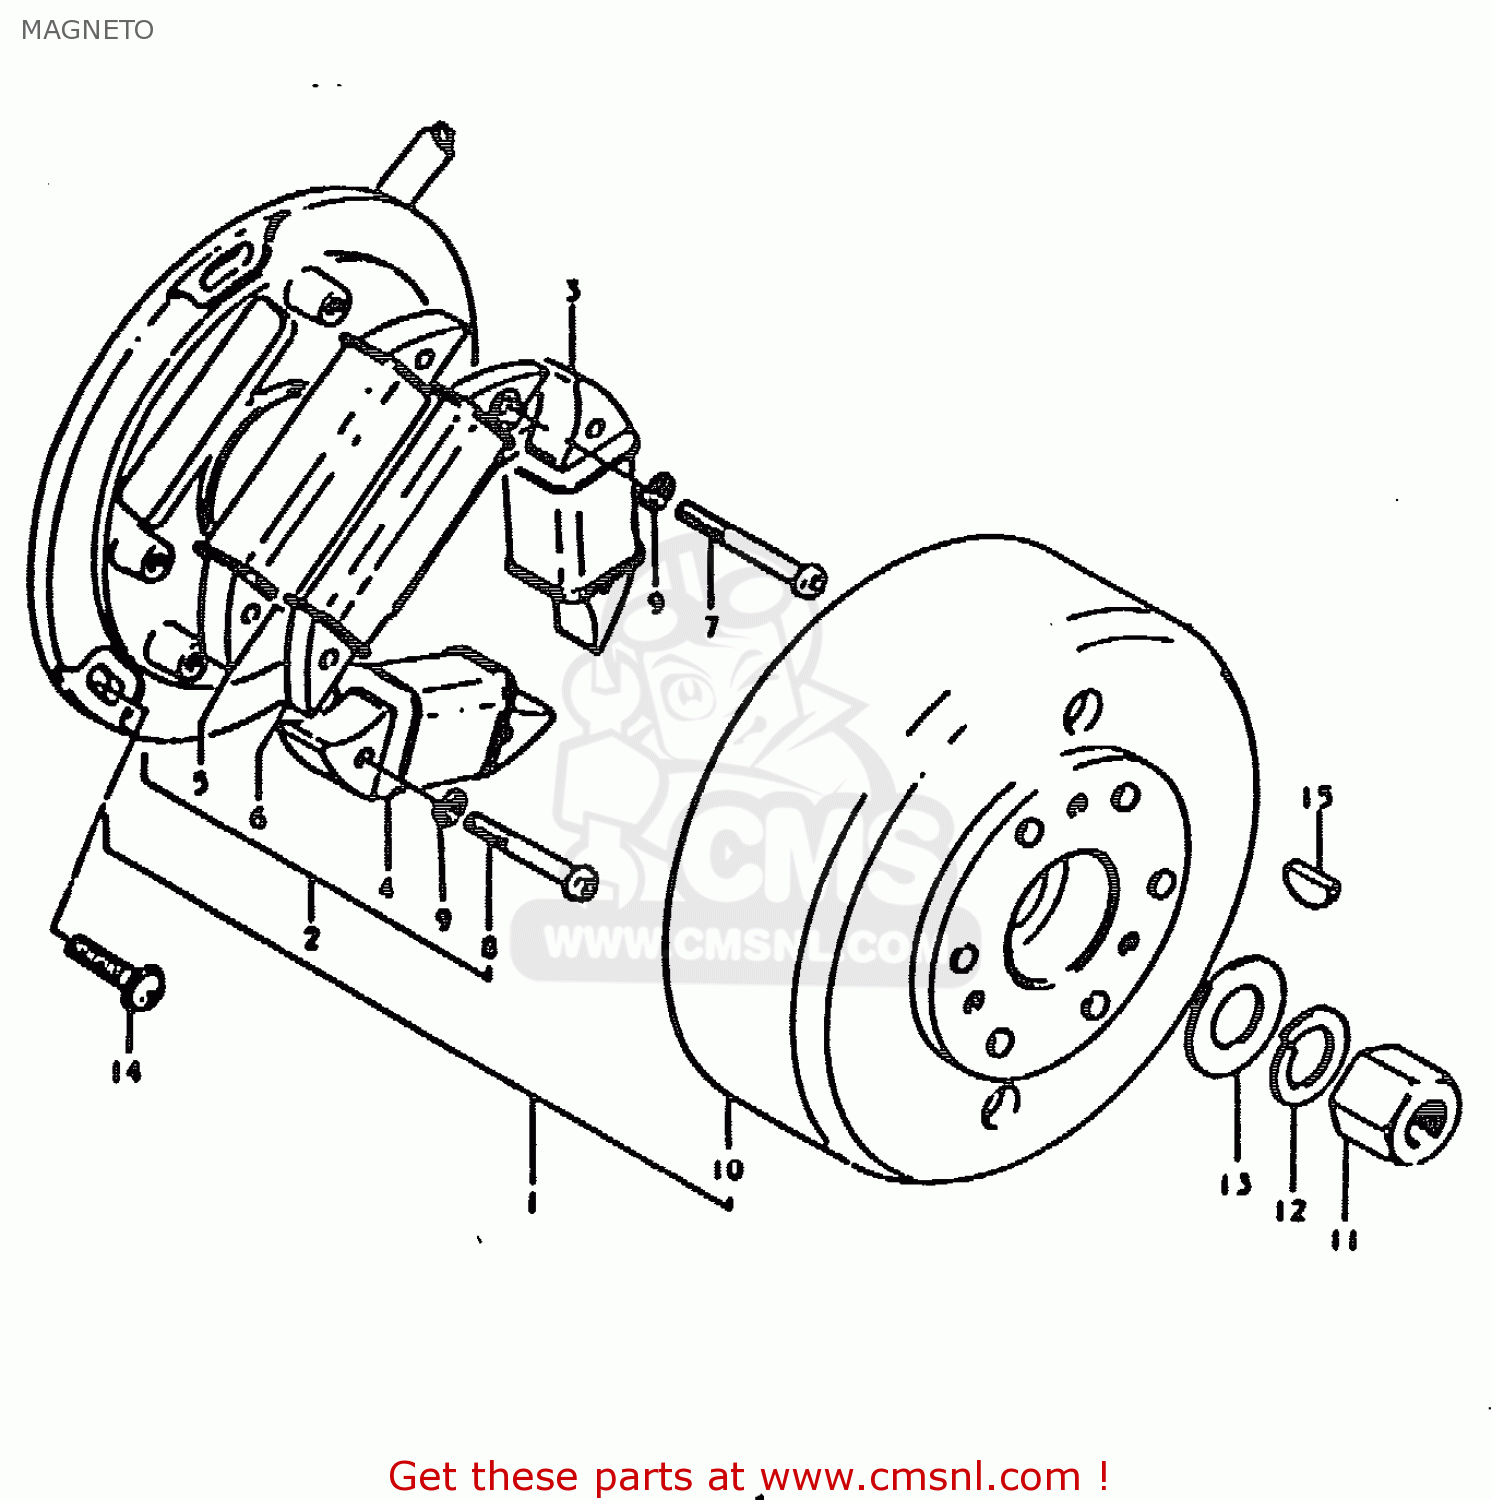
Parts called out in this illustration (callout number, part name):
1	MAGNETO ASSEMBLY
2	STATOR ASSEMBLY
3	COIL,CHARGE
4	COIL,LIGHTING
5	COIL
6	COIL,PULSER
7	SCREW 5X35
8	SCREW 5X20
9	LOCK WASHER
10	ROTOR ASSEMBLY
11	NUT
12	LOCK WASHER
13	WASHER(14X27X3)
14	SCREW(5X14)
15	KEY 4MM
